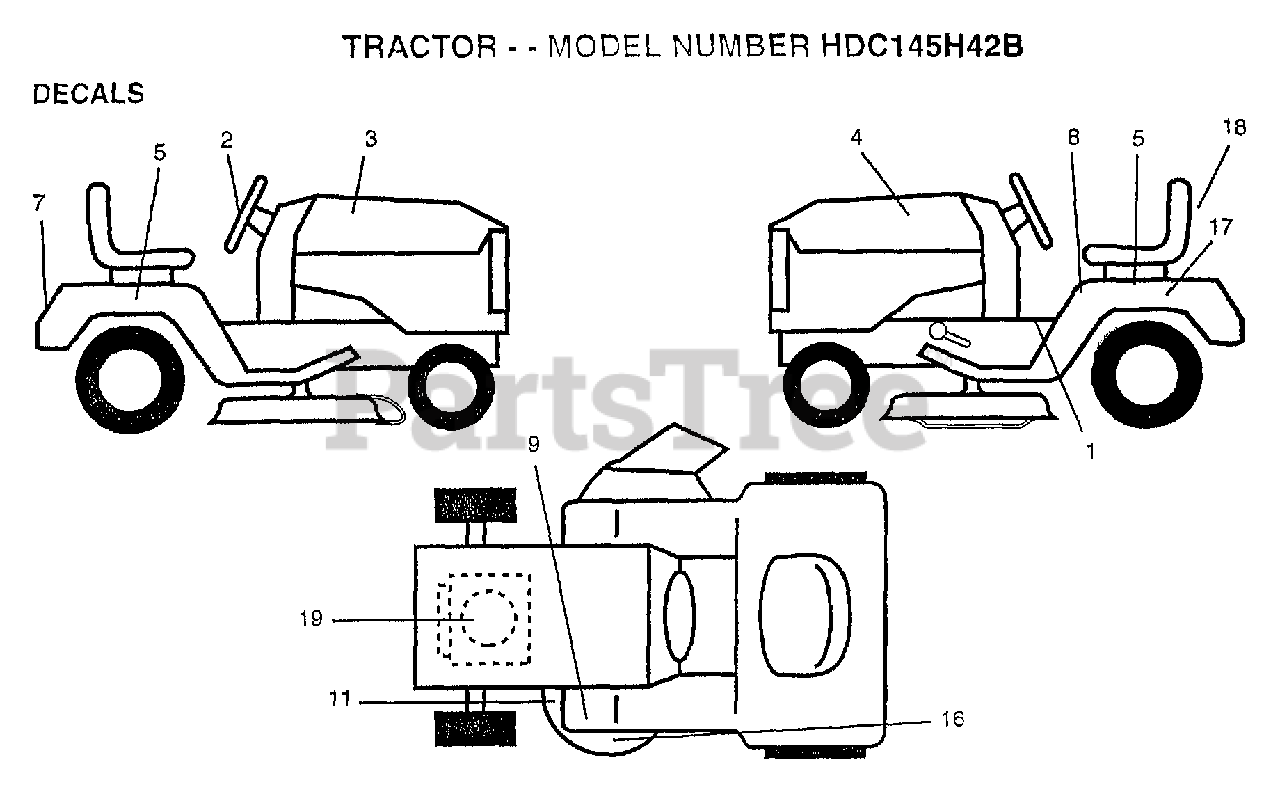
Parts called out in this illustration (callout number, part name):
1	"DECAL-SADDLE,INST"
2	"DECAL WHEEL,STEER"
3	"DECAL-HOOD,RH"
4	"DECAL-HOOD,LH"
5	"DECAL FENDER,SD"
7	"DECAL FENDER,LOGO"
8	"DECAL FENDER,DANG"
9	DECAL CLUT/BRAKE
11	DECAL
16	"DECAL DECK,MULCH"
17	DECAL.BATRY.3-3908
18	"DECAL SEAT,ACC"
19	"DECAL REPLCMT,ENG"
